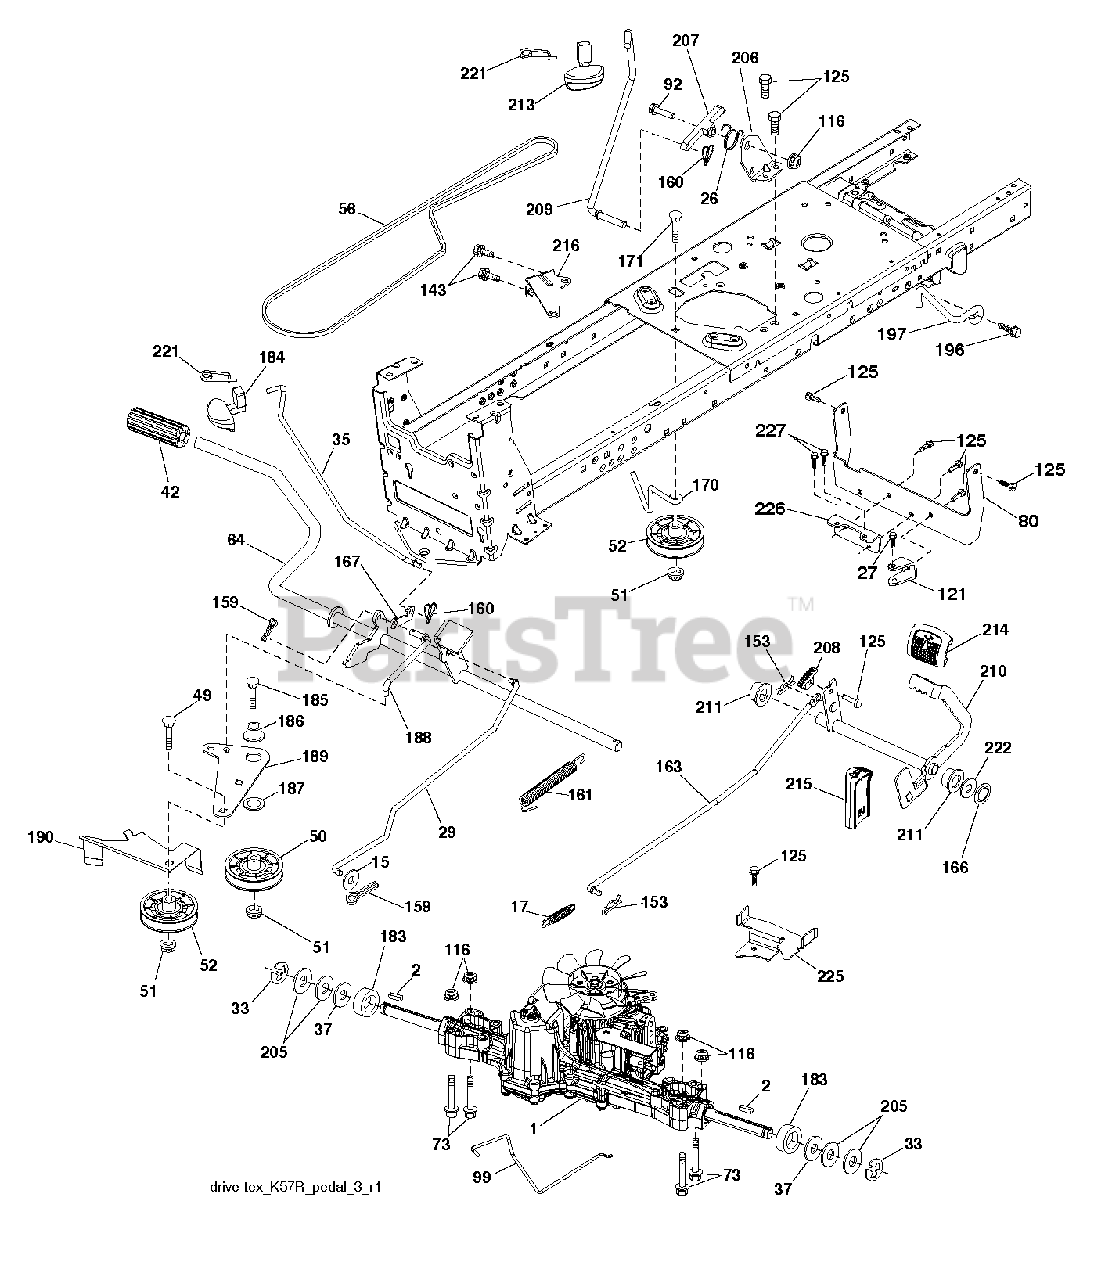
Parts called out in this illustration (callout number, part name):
2	SQUARE KEY
15	WASHER
17	SPRING.BRAKE.K46.GREEN
26	SPRING.RETURN.CRUISE
29	ROD.BRAKE.K46
35	ROD .BRAKE. PARKING. GT. HUSQ.
42	PEDAL COVER T
50	IDLER.FLAT.910.OFFSET
51	NUT LOCK FLG 3/8-16 UNC
52	IDLER.V-GROOVE.910.OFFSET
56	V-BELT.MOWER.92.40.42/K46
64	SHAFT.ASM.PEDAL.BRK.CNTR
80	STRAP.TORQUE.K46.K57R.TT
92	BOLT
99	ROD.SPRING.BYPASS.K46.LT.Z
116	NUT LOCK HEX FLANGE 5/16-18
121	BRACKET.TORQUE.K57R.3POINT
125	SCREW
143	SCREW LT
153	RETAINER M
159	COTTER PIN
160	RETAINER CLIP
161	SPRING, RETURN LT
163	ROD.CONTROL.K57R.K46
166	NUT.PUSH.625
167	LATCH.BRAKE.SPRING
170	KEEPER.V-IDLER.CENTER.
183	SPACER AXLE
184	RB HANDLE.PARKG.BRK.HUS/PRED
186	SPACER.RETAINER
187	WASHER 12/32X2X10GA
188	RP LINK.CLUTCH.GROUND.DRIVE
189	BELLCRANK.GROUND.DRIVE.TEX.
190	KEEPER.BELLCRANK.DRIVE
196	SCREW 3/8-16X1
197	LINK.CLUTCH.ANIT-ROTAT
206	BRACKET.MOUNT.CRUISE.LATCH
207	LATCH.CONTROL.CRUISE
208	GEAR.SECTOR.CONTROL.CR
209	ROD.CONTROL.CRUISE.GT.
210	ROCKER.ASM.PEDAL.CONTR
211	BEARING.NYLON
213	KNOB.CONTROL.CRUSIE.HU
214	PEDAL.FORWARD.PAD.TEX
215	PEDAL.REVERSE.TEX.GT.4
216	BRACKET.PULLEY.IDLER.W/TEX
221	RETAINER.SPRING.CLIP.H
222	WASHER 21/32 X 1-1/4 X 10 GA.
225	KEEPER.BELT.TRANSAXLE.K46
226	BRACKET.MOUNT.TORQUE.K46.TLT
227	SCREW
